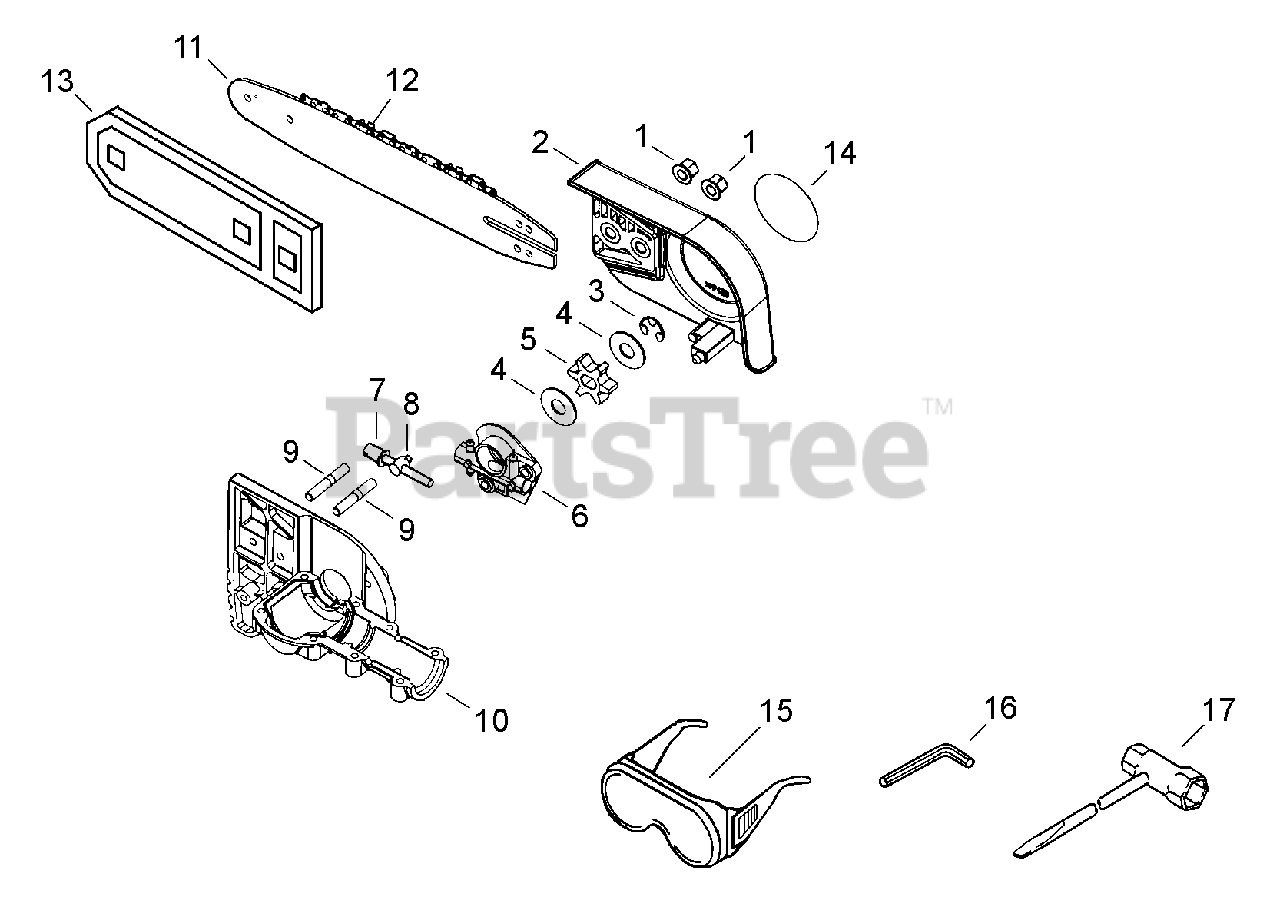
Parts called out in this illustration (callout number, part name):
1	NUT, FLANGE M6
2	GUARD, SPROCKET
3	RING, RETAINING Ø0.300
4	WASHER 10.2×24.5×1.2
5	SPROCKET, DRIVE
6	AUTO-OILER ASSY
8	TENSIONER, CHAIN
9	BOLT, STUD 6
10	CASE ASSY, LOWER GEAR
11	GUIDE BAR, 12"
12	SAW CHAIN 12" - MICRO-LITE
13	SCABBARD 12"
14	LABEL, RECOIL STARTER
15	GLASSES, SAFETY
16	WRENCH, ALLEN 4 MM
17	T-WRENCH 10×19 MM
